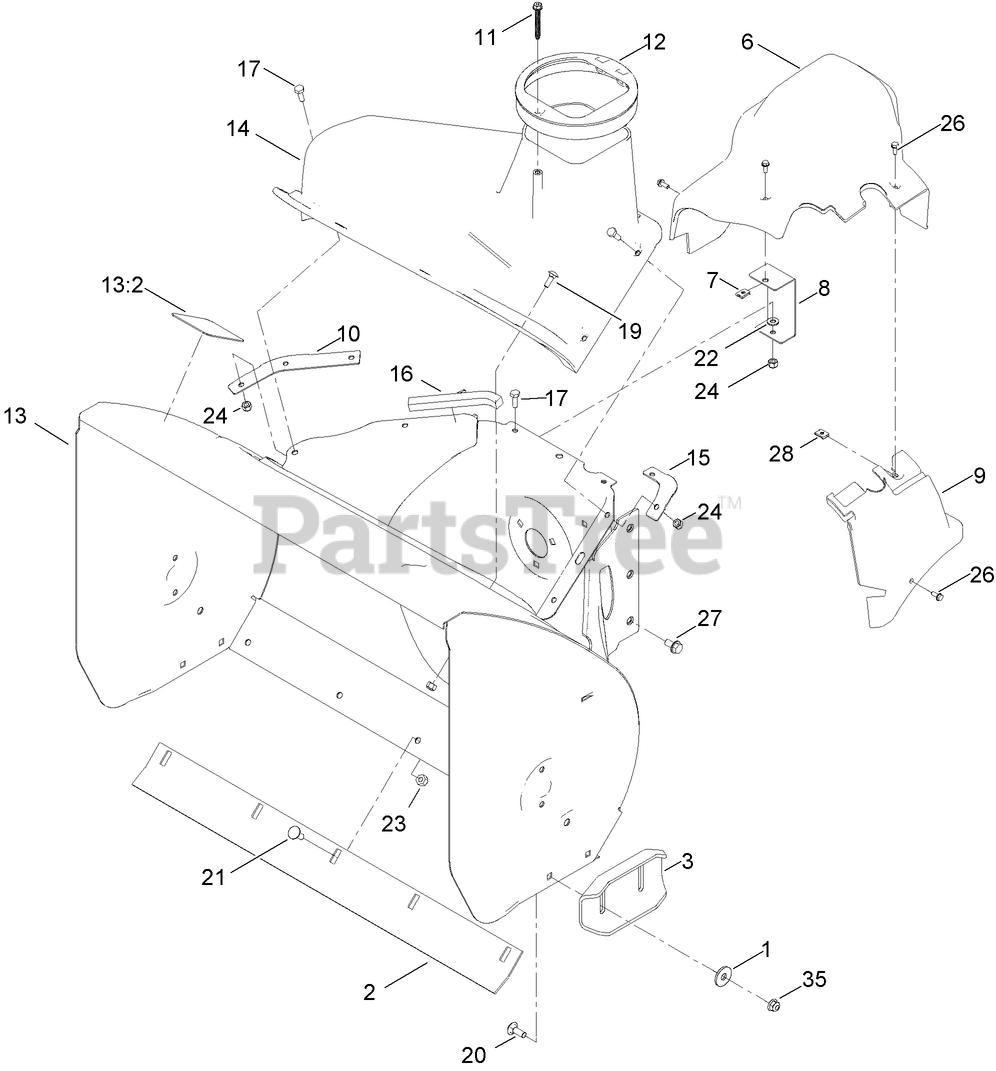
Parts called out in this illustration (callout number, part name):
1	WASHER
2	SCRAPER-FIXED
6	COVER-BELT
7	NUT-SPEED
8	BRACKET-COVER, CLIP NUT
9	COVER-EXTENSION, BELT
10	SEAL-FLANGE, COVER
11	SCREW-HWH, PLASTITE
12	GUIDE-CHUTE
13	HOUSING-AUGER, 28 INCH
13:2	DECAL-DANGER
16	SEAL-HOUSING
17	SCREW-HH
19	BOLT-CARR
20	SCREW-CARR
21	SCREW-CARR
22	WASHER-FLAT
23	NUT-LOCK, NI
24	NUT-LOCK, NI
26	SCREW-HWH
27	SCREW-HWHTF
28	NUT-SPEED
35	NUT-HF, NI
